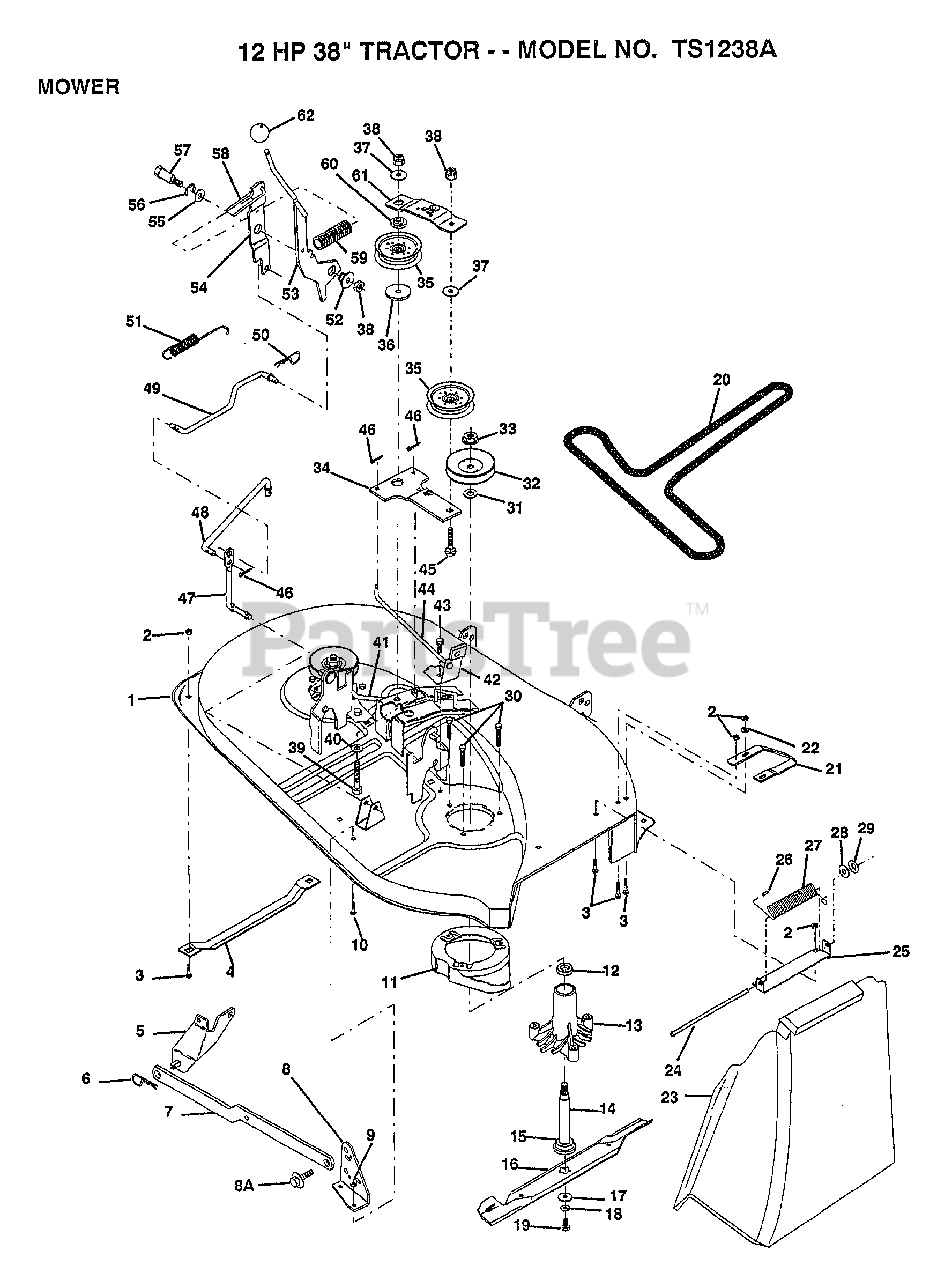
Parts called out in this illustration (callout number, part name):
3	BOLT
4	RUNNER-LH M
5	BRKT ASM SWAY BAR
8	BRKT DECK SW BAR
8A	BOLT SHD 5/16-18
9	NUT
10	BOLT
12	BEARING
13	HSG ASM MANDREL
15	BEARING.BALL
16	"BLADE.38""V.MULCH"
17	WASHER BLADE
19	BLADE BOLT
20	BELT-V.88.12.MW
21	RUNNER RH
22	WASHER M
23	DEFLECTOR-SHLD T
24	ROD-HINGE T
25	BRKT DEFLECTOR
26	CAP-SLEEVE LT
27	SPRING TORSION
28	WASHER
29	NUT PUSH M
30	BOLT.5/16-18X1.25
31	WASHER
34	IDLER ARM ASSY
35	FLAT IDLER PULLEY
36	SPACER RETAINER
37	WASHER GT
39	BOLT
40	WASHER GT
41	BRAKE ROD LH
42	BRAKE ASM
43	SCREW
44	BRAKE ROD RH
45	BOLT
47	PIVOT ROD
48	CLUTCH ROD SECOND
49	"ROD, CLUTCH PRIM"
50	RETAINER M
51	RETURN SPRING
52	BUSHING
53	CLUTCH ARM PRI AS
54	CLUTCH ARM SECOND
55	WASHER
56	RING
57	SHOULDER BOLT
58	SPRING KEEPER
60	RETAINER SPACER
61	IDLER ARM STIFF
62	KNOB T(3/8 HOLE)
